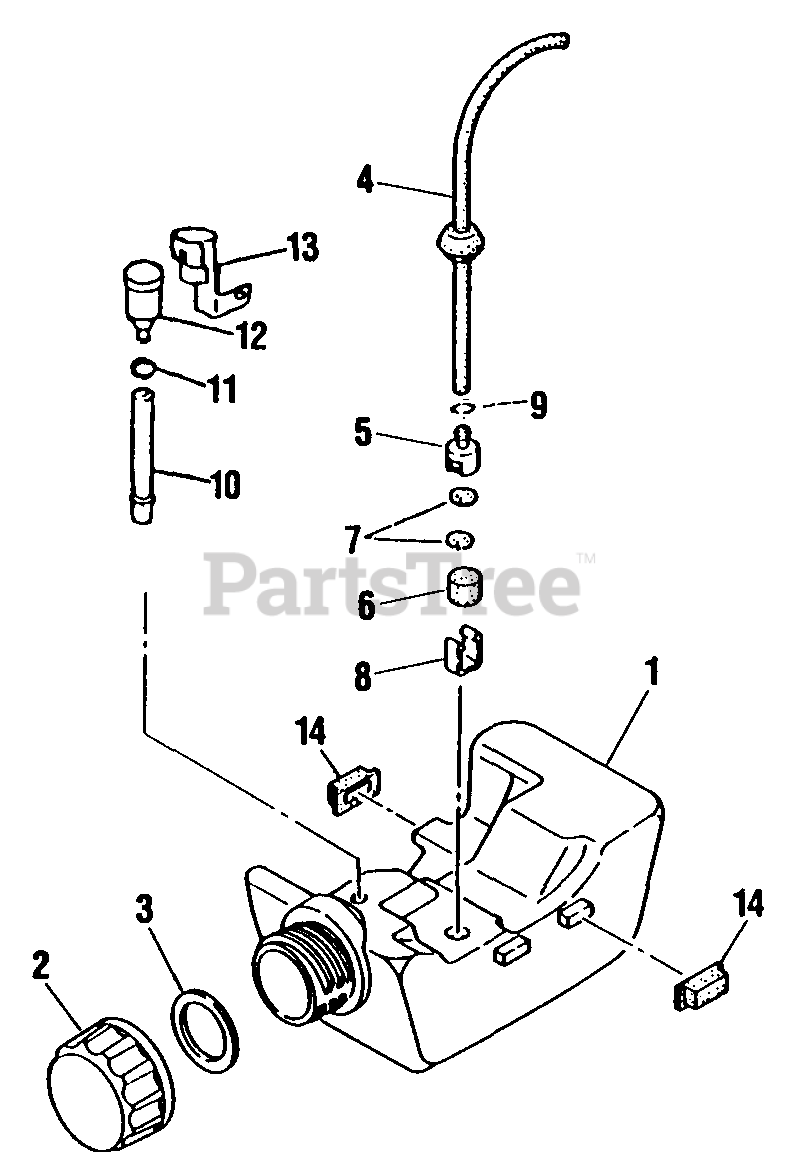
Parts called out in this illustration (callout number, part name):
1	TANK, FUEL
2	CAP, FUEL
3	GASKET, FUEL CAP
4	PIPE, FUEL
5	WEIGHT, FUEL FILTER
6	FILTER, FUEL
7	SCREEN, FUEL INLET
8	CLIP, FILTER
9	CLIP Ø6
10	PIPE, BREATHER
11	CLIP Ø6
12	VALVE
14	CUSHION, TANK
